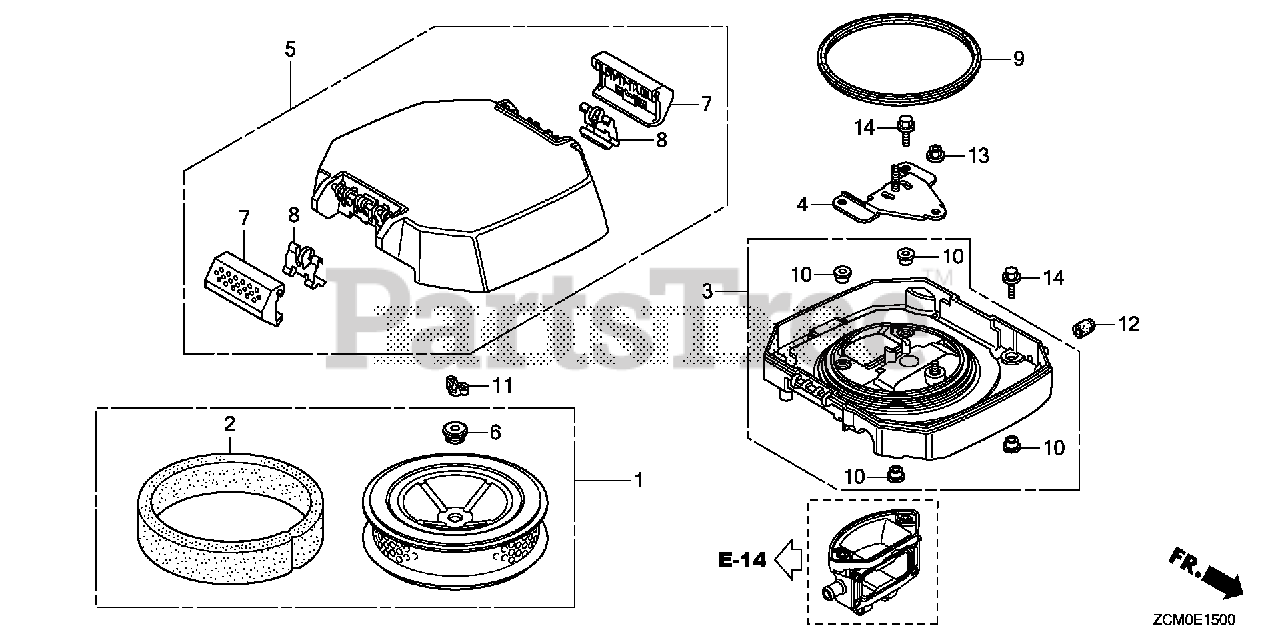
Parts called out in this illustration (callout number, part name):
1	ELEMENT, AIR CLEANER
2	FILTER (OUTER)
3	HOUSING, AIR CLEANER
4	STAY, AIR CLEANER ELEMENT
5	COVER, AIR CLEANER
6	GROMMET, AIR CLEANER
7	KNOB, AIR CLEANER COVER
8	SPRING, AIR CLEANER HOUSING COVER
9	GASKET, AIR CLEANER HOUSING
10	COLLAR, FAN COVER
11	NUT, TOOL BOX SETTING
12	CAP, SEALING
13	NUT, FLANGE (6MM)
14	BOLT, FLANGE (6X18)
